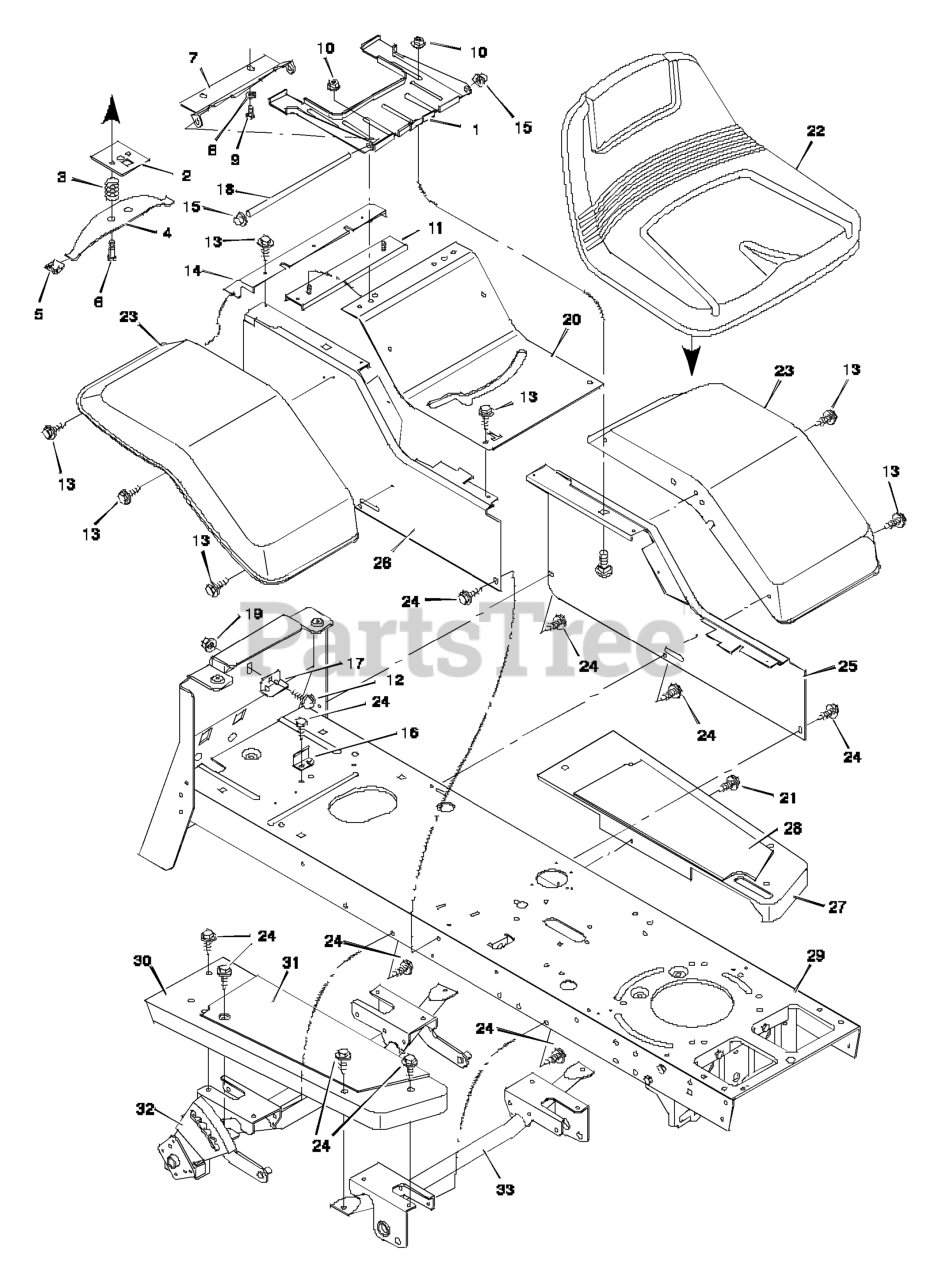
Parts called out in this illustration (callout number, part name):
1	Bracket, Seat
2	Plate Assembly, Switch
3	Spring, Compression
4	Spring, Seat
5	Glide, Spring
6	Bolt, Shoulder
7	Support, Seat
8	Lockwasher
9	Bolt, Hex
10	Locknut, Flange
11	Channel Assembly
12	Bolt, Carriage
14	Insert, Rear
15	Push On Cap
16	Clip, Battery
17	Clamp, Battery
18	Rod, Pivot
19	Locknut
20	Panel, Top
21	Fastener, Panel
25	Panel, Left
26	Panel, Right
27	Running Board, Left
28	Mat, Left
29	Frame Channel
30	Running Board, Right
31	Mat, Right
32	Lifter and Support Assembly
33	Support Assembly, Front
